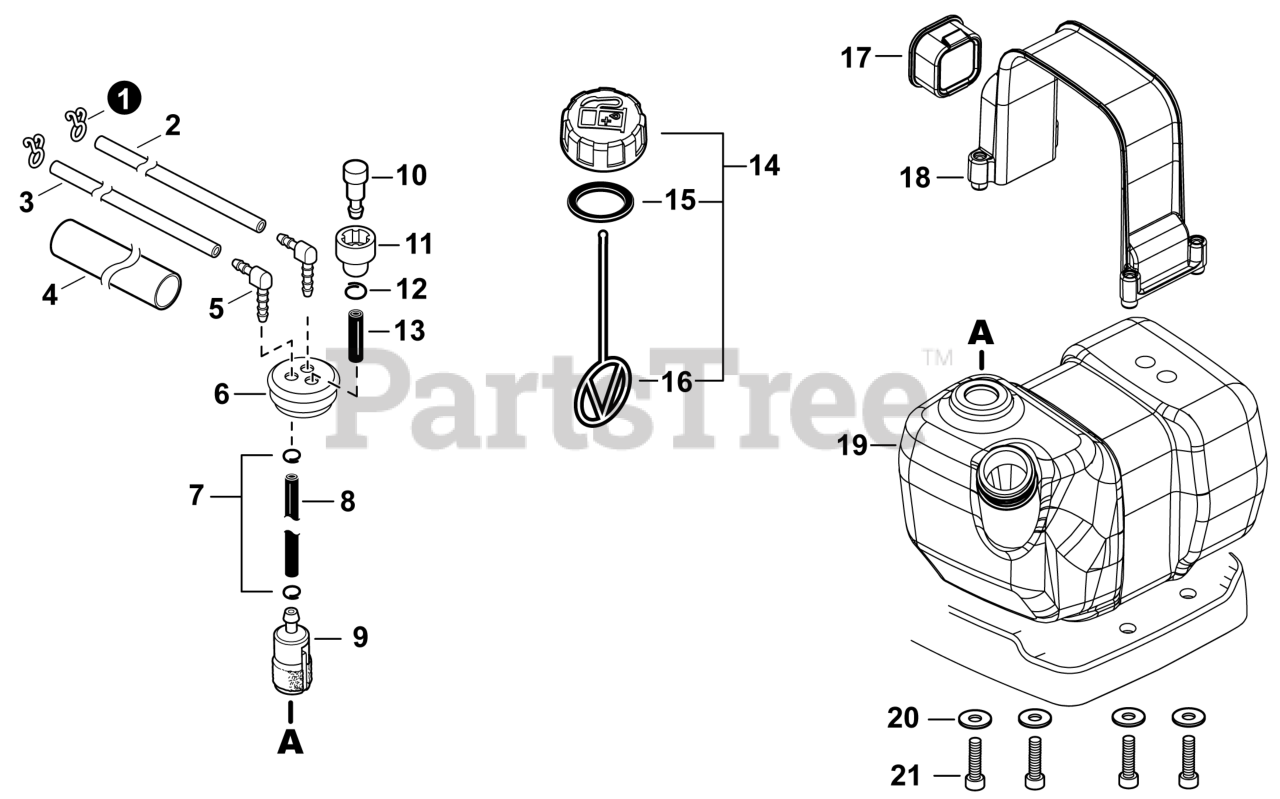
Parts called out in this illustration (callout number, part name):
1	CLIP, SPRING 5.2
2	PIPE, FUEL 3x6x170 YELLOW
3	PIPE, FUEL 3.5x6x160 CLEAR
4	TUBE, INSULATOR 16x18x90
5	CONNECTOR, PIPE
6	GROMMET, FUEL
8	PIPE, FUEL 3x5x210 BLACK
9	FILTER, FUEL
10	VENT ASSY
11	HOLDER, VENT
12	CLIP 6.5 MM
13	PIPE, FUEL 3x6x30 BLACK
14	CAP ASSY, FUEL
15	GASKET, FUEL CAP
16	CONNECTOR, CAP L= 123
17	CUSHION
18	BAND, FUEL TANK
19	TANK, FUEL
20	WASHER 5.5x16x0.8
21	BOLT 5x20
